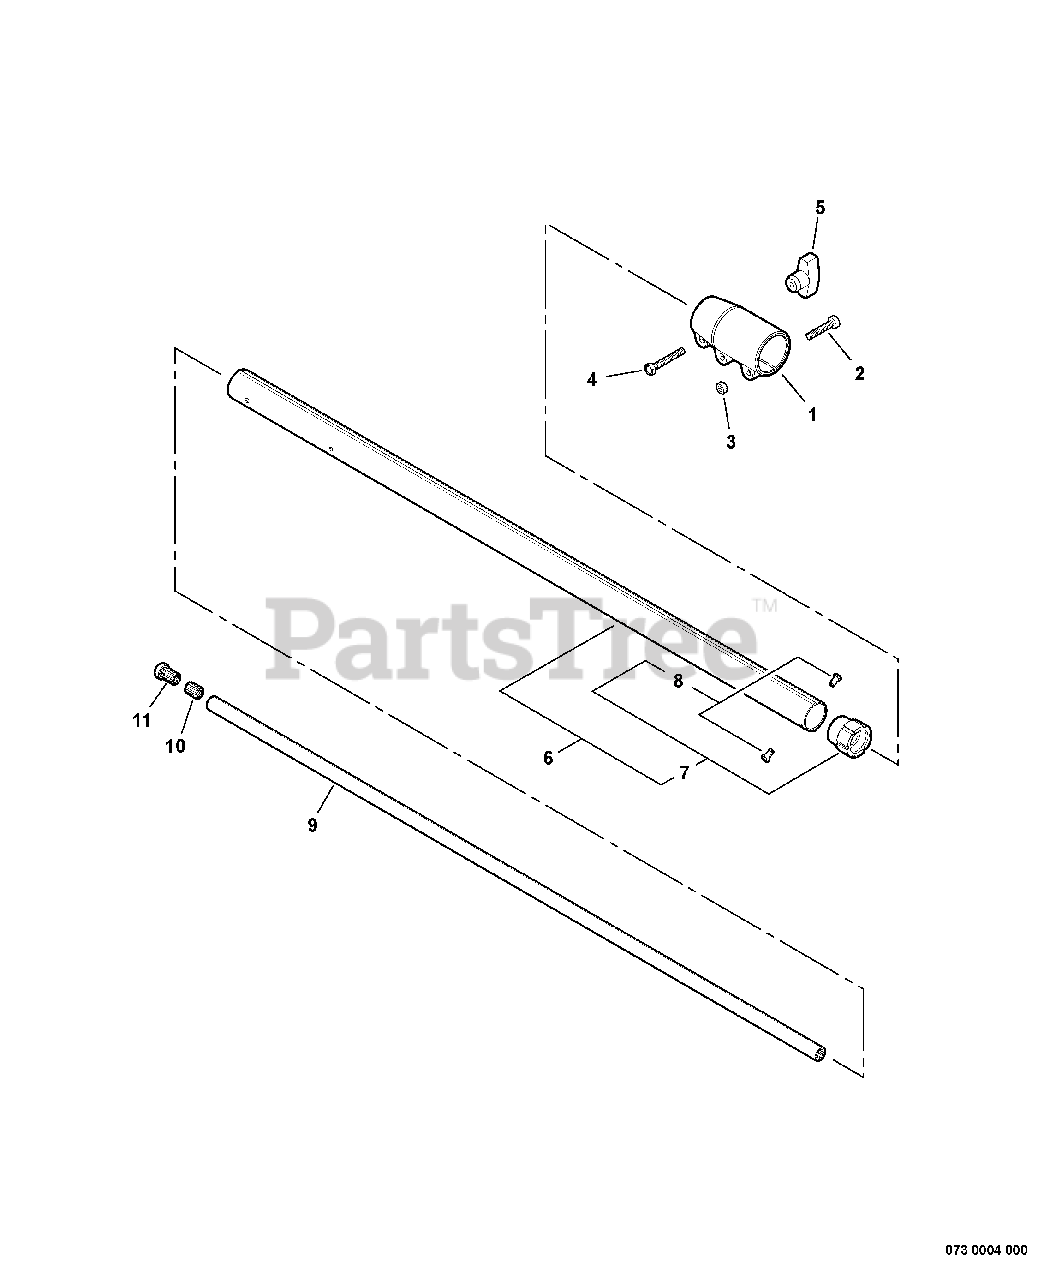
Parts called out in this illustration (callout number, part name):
1	COUPLING
2	SCREW - 5X20
4	BOLT - 6X25
5	THUMBSCREW
6	MAIN PIPE ASSY - BLACK
7	BEARING HOLDER ASSY
9	DRIVESHAFT - UPPER
10	SOCKET - INNER
11	SOCKET - OUTER
